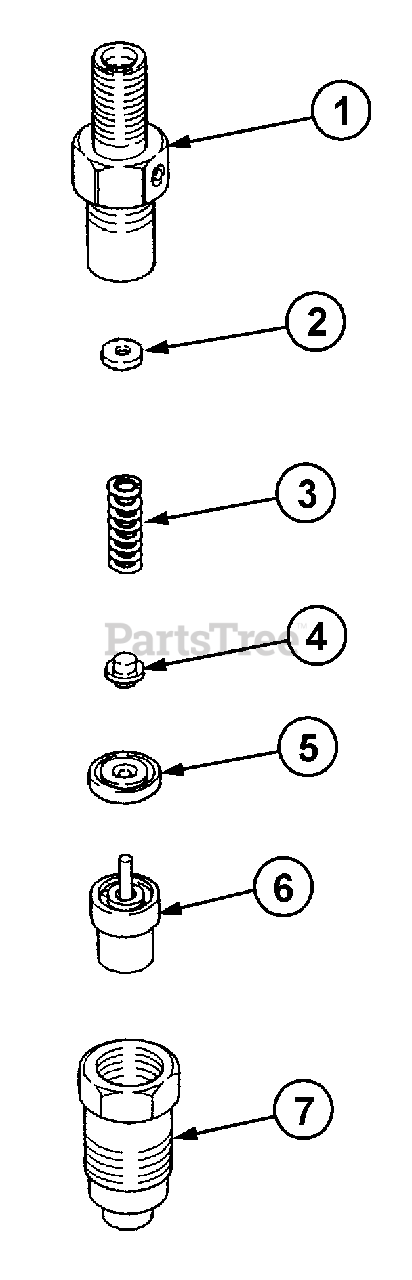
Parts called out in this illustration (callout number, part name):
1	Body Sub Assy
2	Washer, t=1.25
3	Spring, Pressure
4	Pin, Pressure
5	Piece, Distance
7	Nut, Retaining
